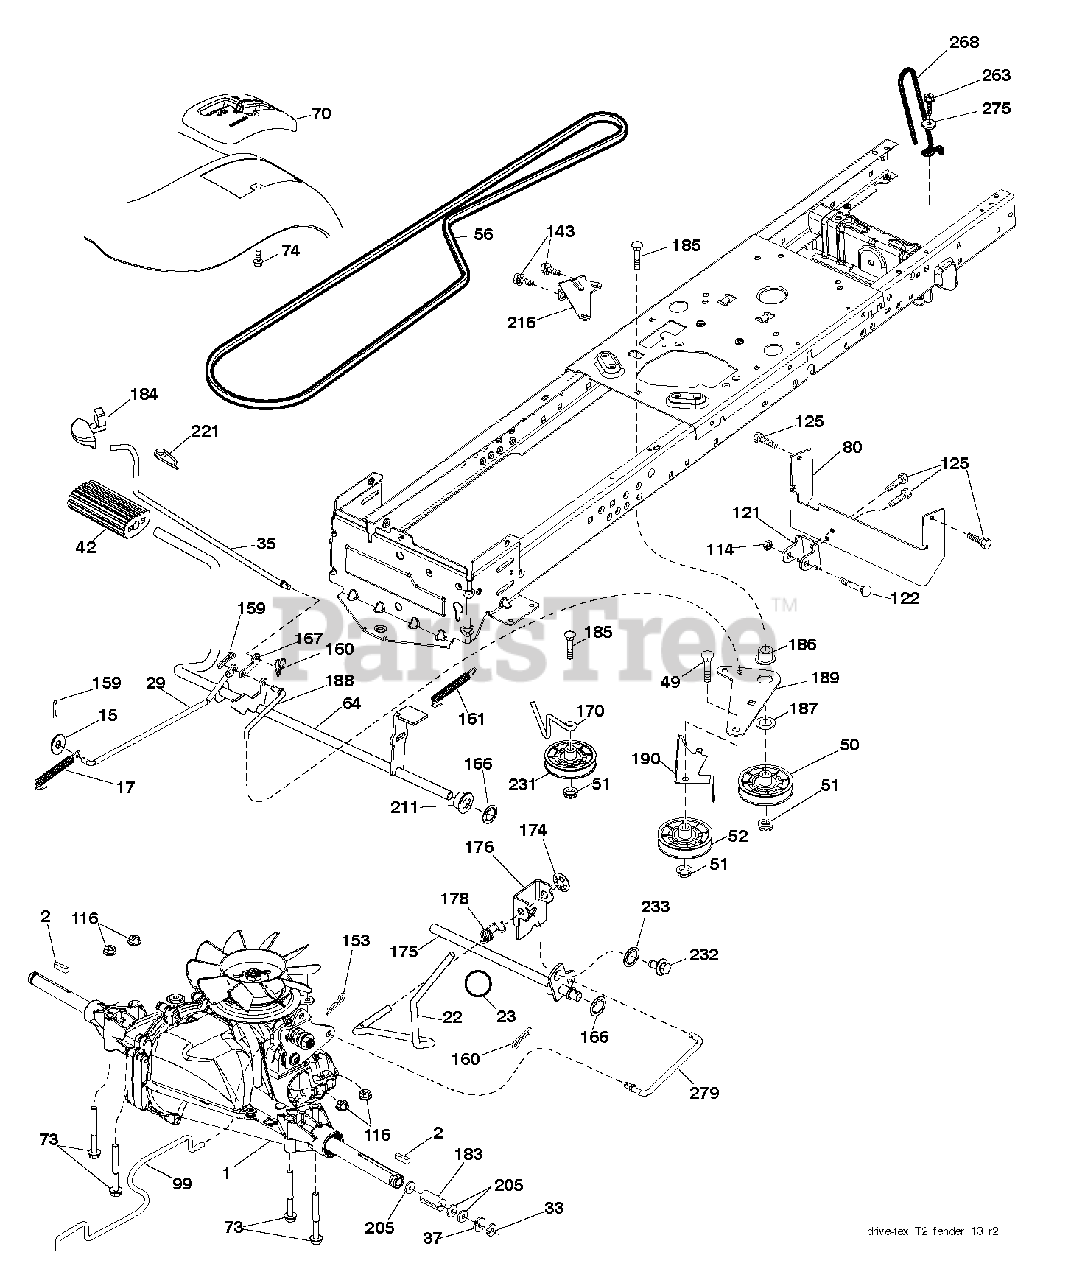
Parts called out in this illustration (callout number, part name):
2	SQUARE KEY
17	SPRING.BRAKE.HG3000/3500
22	ROD.SHIFT.FENDER.TLT.2006
23	PISTOL KNOB
29	ROD.BRAKE.T2.TEX
33	E-RING LT
35	Parking Brake Rod, GT Husq
42	PEDAL COVER T
49	BOLT
50	IDLER.FLAT.910.OFFSET
51	NUT LOCK FLG 3/8-16 UNC
52	IDLER.V-GROOVE.910.OFFSET
56	Ground Drive Belt, T2 HP CE
64	SHAFT.ASM.PEDAL.BRAKE.
70	CONSOLE.SHIFT.STL.HYD.BLACK
73	BOLT HEX 5/16-18 GR 5
74	SCREW.HI-LO.CONSOLE
80	Strap.Torque.T2
99	ROD.ASM.BYPASS.SPRING.T2.FS
114	NUT.71038.31-18.HEX.NYLOCK
116	NUT LOCK HEX FLANGE 5/16-18
121	BRACKET STRAP TORQUE
122	BOLT.5/16-18X2.5
125	SCREW
153	RETAINER M
159	COTTER PIN
160	RETAINER CLIP
161	SPRING, RETURN LT
166	NUT.PUSH.625
167	LATCH.BRAKE.SPRING
170	KEEPER.CENTER SPAN.1.688
174	NUT.PUSH.500.2006
175	SHAFT.ASM.SHFT.T2.TLT
176	ARM.CLEVIS.ROD.SHIFT
178	SPRING.SHIFT.GT2006
183	SPACER, AXLE PVST
184	HANDLE.PARKG.BRK.HUSQ/PRED.667
186	SPACER.RETAINER
187	WASHER 12/32X2X10GA
188	LINK.CLUTCH.GROUND.DRIVE
189	BELLCRANK.GROUND.DRIVE.TEX.
190	KEEPER.BELLCRANK.DRIVE
211	BUSHING.SHAFT.BRAKE.HAND
216	BRACKET.PULLEY.IDLER.W/TEX
221	RETAINER.SPRING.CLIP.H
231	IDLER.V-GROOVE.1.688.OFFSET
232	BOLT FIN HEX 7/16-14 X 1
233	WASHER SERRATED
263	SCREW, 3/8-16X3/4
275	WASHER
279	LINK.SHIFT.T2
